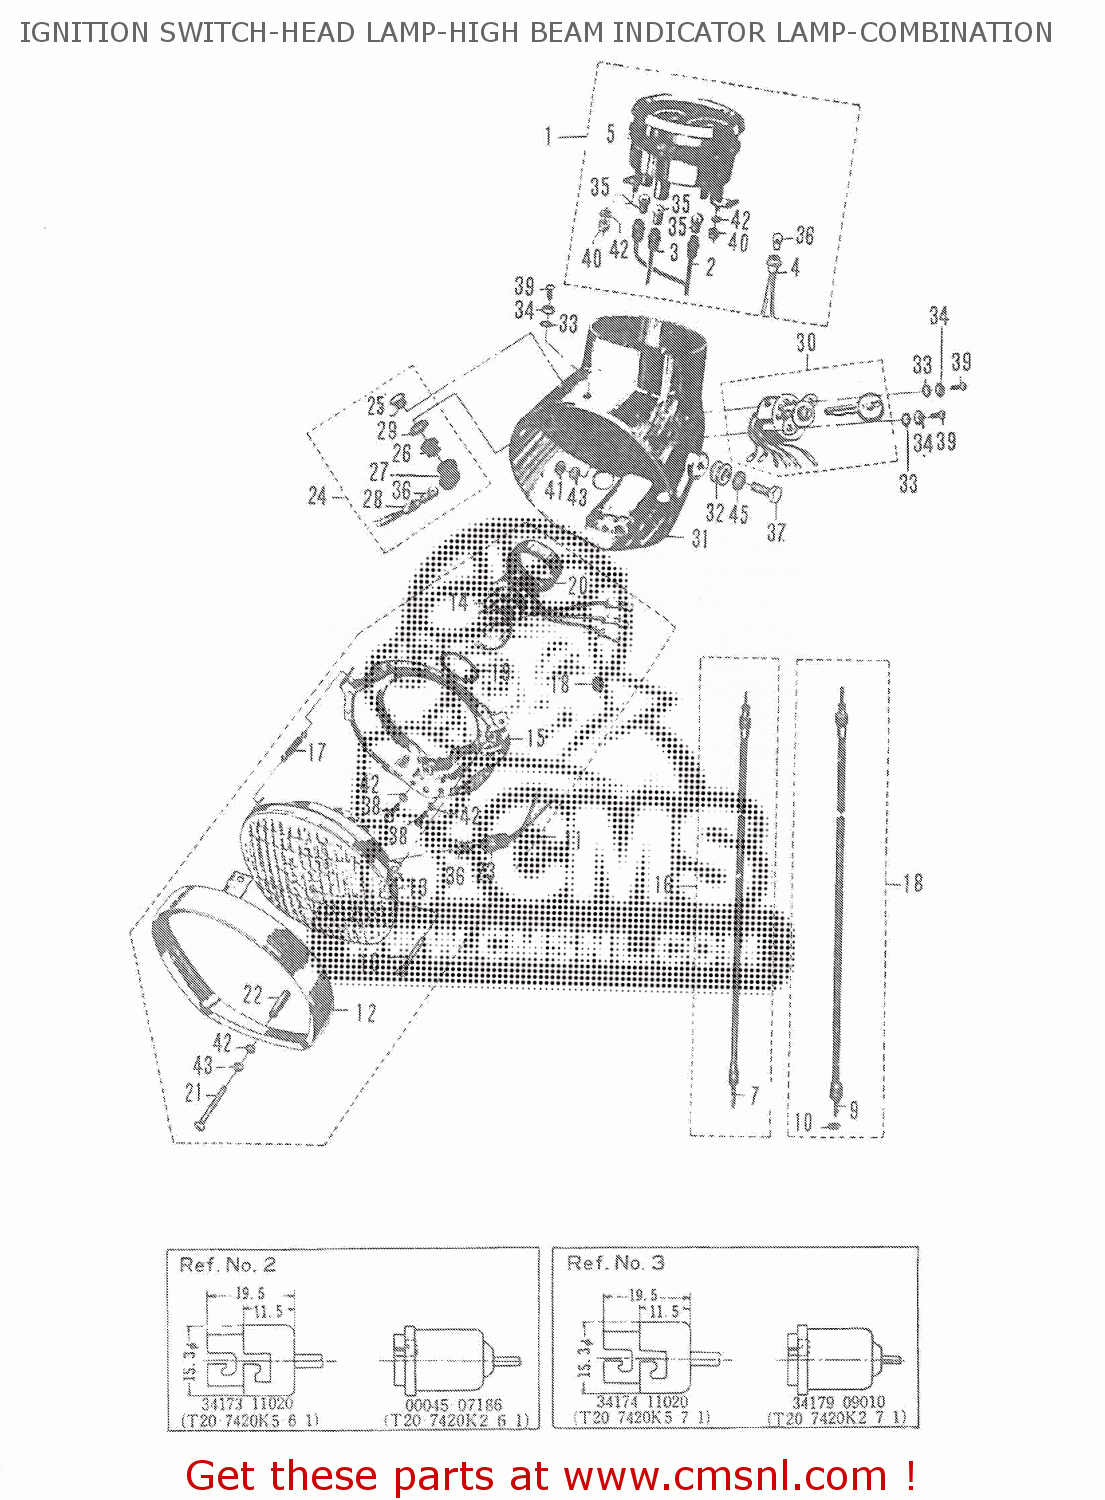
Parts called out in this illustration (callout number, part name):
1	COMBINATION METER ASS'Y
2	SPEEDOMETER LAMP SOCKET
3	NEUTRAL LAMP SOCKET
4	TURN SIGNAL INDICATOR LAMP SOCKET
5	COMBINATION METER GASKET
6	SPEEDOMETER CABLE ASS'Y
7	SPEEDOMETER INNER CABLE
8	TACHOMETER CABLE ASS'Y
9	TACHEMETER INNER CABLE
10	SEAL,OIL SPEEDOMETER CABLE
11	HEAD LAMP ASS'Y
12	HEAD LAMP RIM
13	HEAD LAMP LENS UNIT
14	HEAD LAMP BULB SOCKET
15	HOUSING
16	SCREW,HEADLAMP ADJUST
17	SPRING,HEADLAMP ADJUST
18	CAP,HEADLAMP BEAM HOLE
19	GASKET,BULB (NAS)
20	CLAMP,BULB
21	HEAD LAMP RIM FITTING SCREW
22	HEAD LAMP RIM FITTING SPACER
23	PARKING LAMP BULB SOCKET
24	LAMP ASSEMBLY,BEAM INDICATOR
25	LENS,LAMP
26	NUT,LENS HOLDER
27	HOLDER,LAMP
28	HIGH BEAM INDICATOR LAMP SOCKET
29	GASKET,LENS (NAS)
30	IGNITION SWITCH ASS'Y
31	HEAD LAMP HOUSING
32	HEAD LAMP HOUSING RUBBER
33	HEAD LAMP RIM FITTING SCREW GASKET
34	WASHER (09165-04004)
35	BULB(12V3.4W,STANLEY,A72A)
36	BULB(12V1.7W,A71A)
37	CROWN HEAD BOLT
38	CROSS HEAD SCREW
39	CROSS HEAD SCREW
40	HEXAGON NUT
41	SMALL HEXAGON NUT
42	LOCK WASHER
43	LOCK WASHER
44	FLAT WASHER
45	SMALL FLAT WASHER
